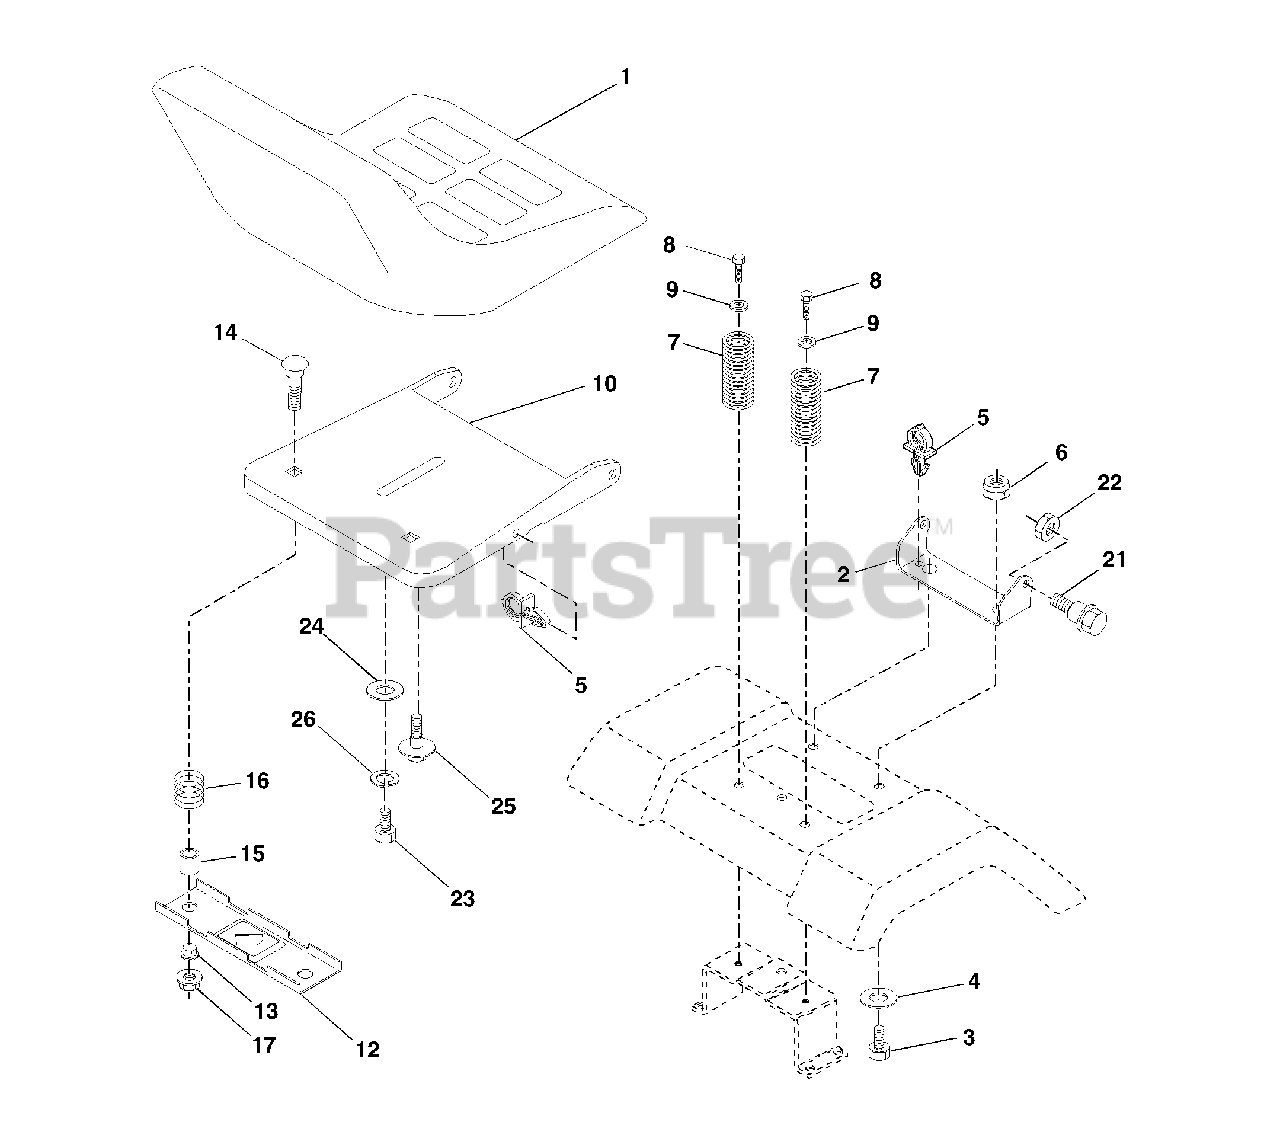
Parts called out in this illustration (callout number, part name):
1	Seat
2	Bracket Seat Pivot
3	Bolt Hex 3/8 - 16 X 1
4	Washer 13/32 X 1 X10Ga.
5	Clip Push-In Hinged
6	Nut Lock Hex w/Ins 3/8 - 16
7	Spring Seat Cprsn 2 250 Blk Zi
8	Screw 3/8-16 x 1.5
9	Washer 13/32 X 1 X 14 Ga
10	Pan Pnt Seat (Blk)
12	Bracket Pnt Mounting Switch
13	Bushing Snap Blk Nyl
14	Bolt Rdhd Sht Nk 1/4 - 20 X 1 -1/2
15	Spacer Split .28 X .96
16	Spring Cprsn
17	Nut Lock 1/4 Lge Flg
21	Bolt Shoulder 5/16-18 Unc-2A
22	Nut Lock Hex w/Ins 5/16 - 18
23	Bolt Hex Black
24	Washer 17/32 X 1-3/16 X 12 Ga
25	Bolt Shoulder 5/16-18 X .62
26	Washer Lock Hvy Hlcl Spr 1/2
